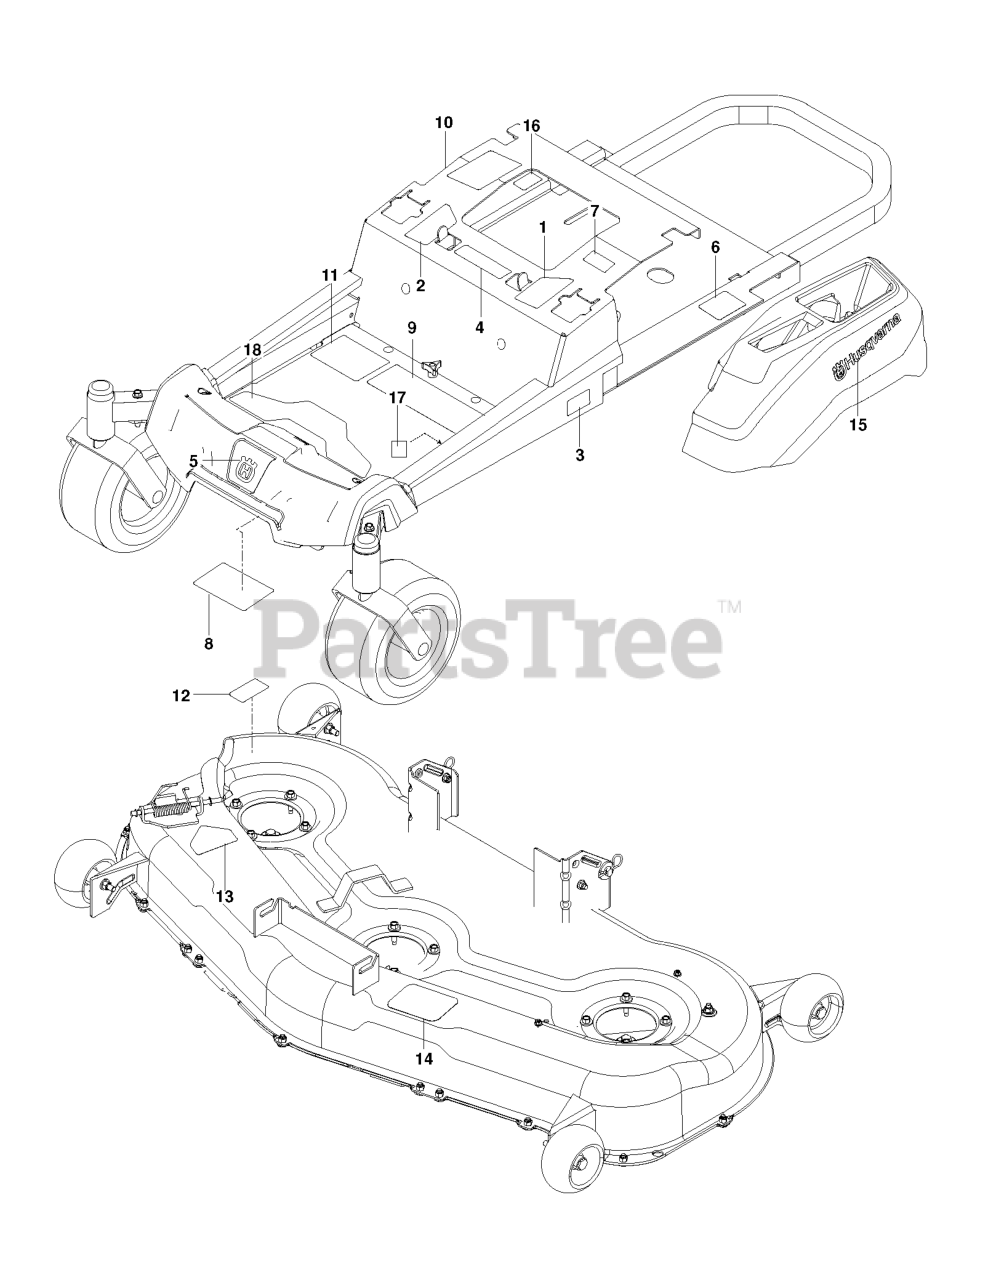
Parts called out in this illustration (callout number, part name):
1	SEAT.TH154.GREY.HUS.ARMREST
2	BRKT.PIVOT.FENDER
3	STRAP
6	NUT
7	SPRING.COMPRESSION.SEAT.BLACK
8	BOLT.5/16-18UNCX3/4 W/SEMS.BLK
10	PAN.ASM.SEAT.3PT
21	BOLT.5/16-18X5/8.SHOULDER
37	NUT.71038.31-18.HEX.NYLOCK
40	HANDLE.SLIDE.SEAT.TEX.GREY
41	SPRING.LATCH.SEAT.TEX
44	WASHER 13/32 X 2-3/8 X 12GA
